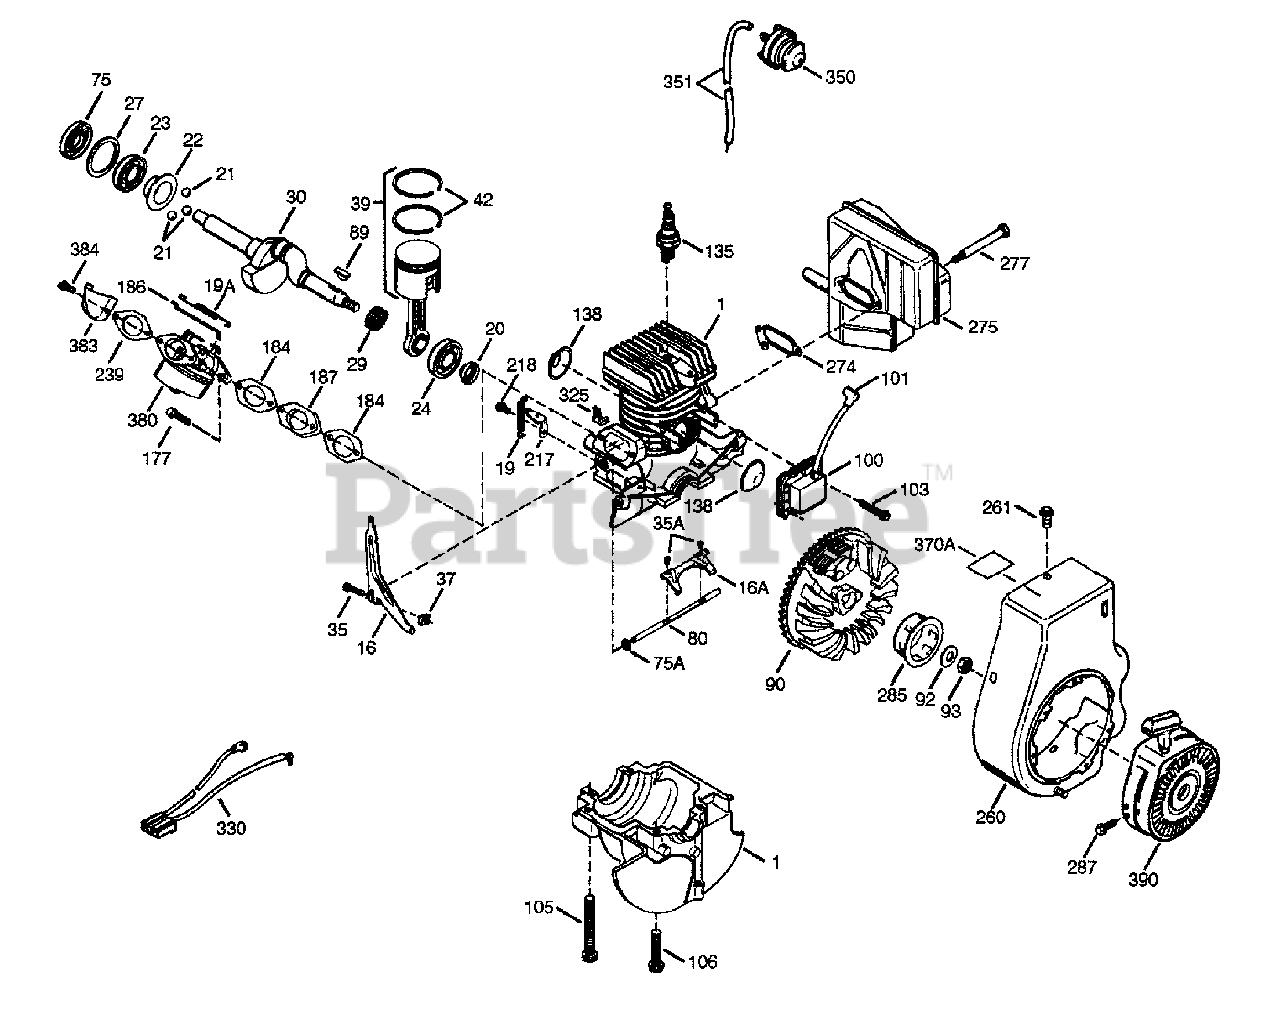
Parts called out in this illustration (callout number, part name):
1	Cylinder Ass'y
16	Governor Lever
16A	Governor Lever
19	Extension Spring
19A	Throttle Link Spring
21	Ball Bearing
22	Slide Ring
23	Ball Bearing
24	Ball Bearing
27	Bearing Retainer
29	Bearing Strip (31 Needles)
30	Crankshaft
35	Screw, 10-32 x 3/4"
35A	Screw, 4-40 x 1/4"
37	Lock Nut, 10-32
39	Piston & Rod Ass'y
80	Governor Shaft
89	Flywheel Key
92	Bell Washer
93	Flywheel Nut
100	Solid State Ignition
101	Spark Plug Cover
103	Screw, Torx T-15, 10-24 x 15/16"
105	Screw, 5/16-18 x 2-3/16"
106	Screw, 5/16-18 x 1-5/8"
135	Resistor Spark Plug
138	Port Cover
177	Screw, 5/32 Allen, 1/4-20 x 5/8"
184	Carburetor Gasket
186	Governor Link
217	Control Lever
218	Screw, 8-32 x 1/2"
239	Air Cleaner Gasket
260	Blower Housing
261	Screw, 5/16-18 x 5/8"
274	Exhaust Gasket
277	Screw, 5/16-18 x 3-13/64"
285	Starter Cup
287	Screw, 8-20 x 21/64"
325	Wire Clip
330	Wire Harness
350	Primer Ass'y
351	Primer Line
370A	Lubrication Decal
380	Carburetor
384	Screw, Torx T-25, 10-32 x 3/8"
390	Rewind Starter
